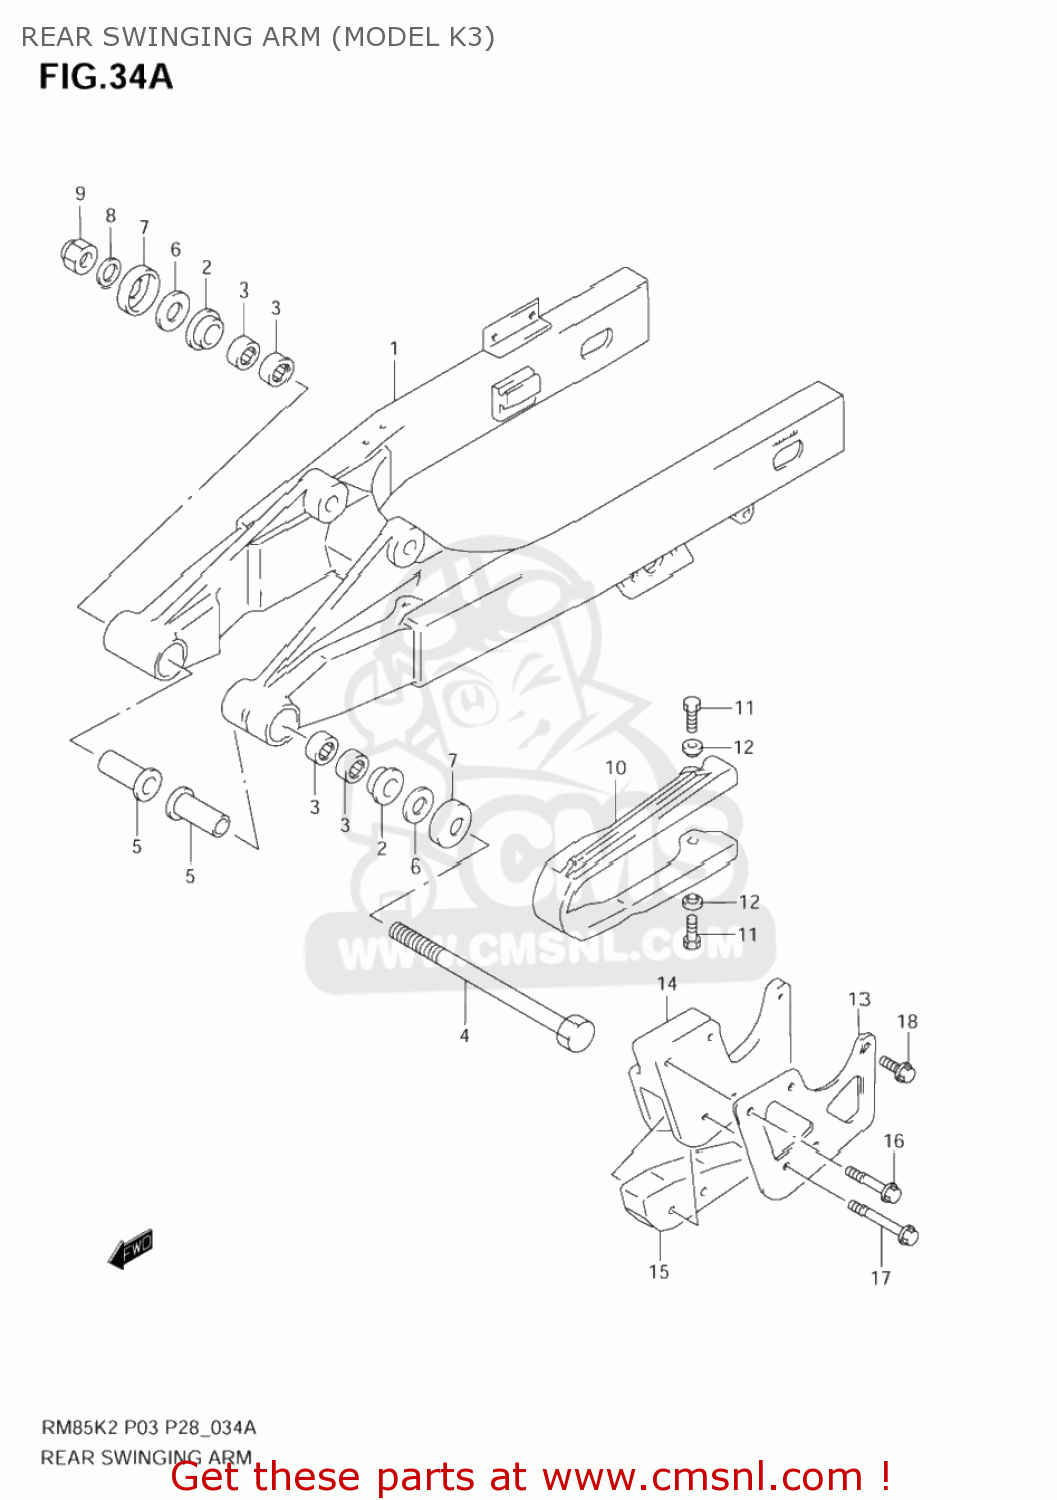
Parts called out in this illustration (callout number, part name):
1	SWINGINGARM ASSY,RR
2	BUSHING,SWGARM PIVOT
3	BEARING(17X24X20)
4	SHAFT,RR SWINGINGARM PIVOT
5	SPACER,RR SWGARM PIVOT
6	WASHER
7	COVER,SWGARM PIVOT
8	WASHER
9	NUT 12MM
10	BUFFER,CHAIN TOUCH DEFENSE
11	BOLT(6X16)
12	WASHER
13	PLATE,GUIDE CHAIN OUTER
14	GUIDE,CHAIN
15	DEFENSE,CHAIN GUIDE
16	BOLT(6X30)
17	BOLT(6X40)
18	BOLT(6X16)
